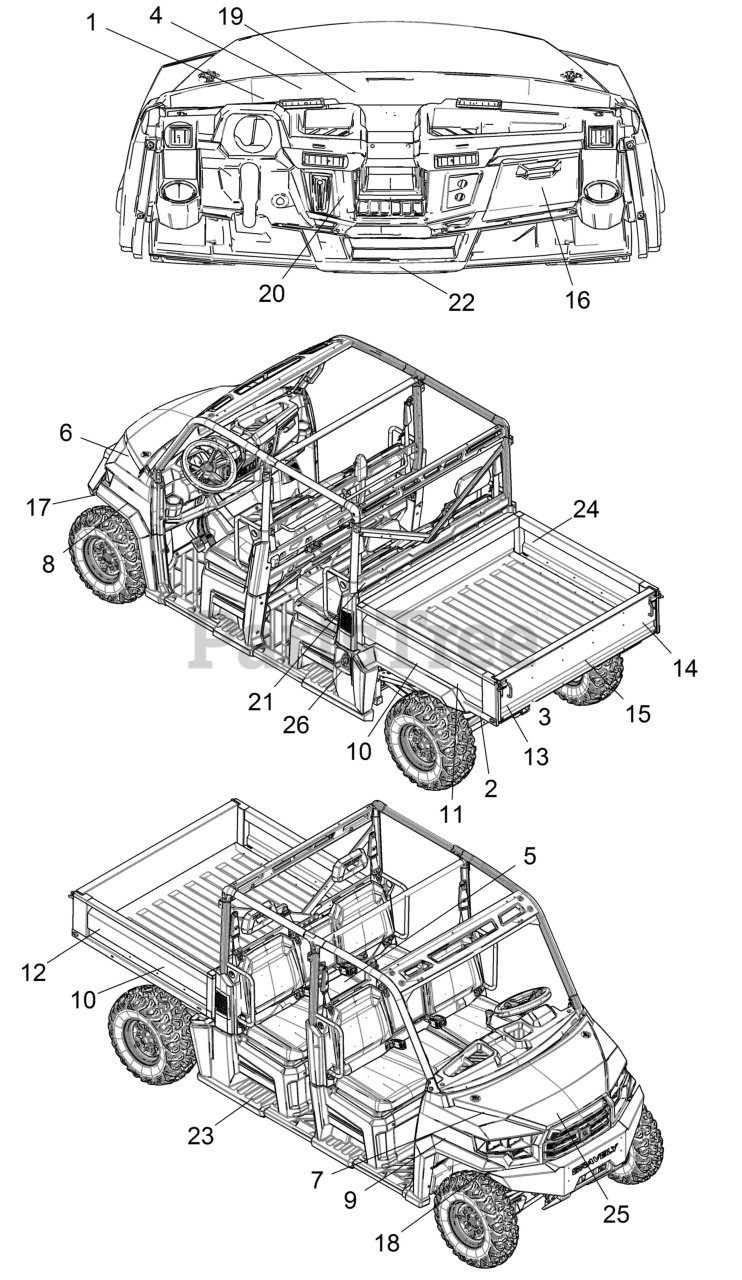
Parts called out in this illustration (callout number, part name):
1	DECAL, AGE WARNING 16
2	DECAL, REFLECTOR RED
3	DECAL-WARNING,TRAILER LOAD
4	LABEL, OPEI COMPLIANCE
5	DECAL, WARNING, PULLEY
6	DECAL, HOOD TOP DIESEL LH
7	DECAL, HOOD TOP DIESEL RH
8	DECAL, HOOD SIDE ATLSJSV, LH
9	DECAL, HOOD SIDE ATLSJSV, RH
10	DECAL, BOX SIDE GRAVELY
11	DECAL, BOX,SIDE, 6000, LH
12	DECAL, BOX,SIDE, 6000, RH
13	DECAL, TAILGATE ATLSJSV, LH
14	DECAL, TAILGATE AWD RH
15	DECAL, TAILGATE GRAVELY CENTER
16	DECAL, GLOVEBOX COVER
17	DECAL, REFLECTOR AMBER LH
18	DECAL, REFLECTOR AMBER RH
19	DECAL, WARNING DISC GRAVELY
20	DECAL, CAUTION SHIFT/BRAKE
21	DECAL, ROPS, 6000
22	DECAL,WARNING PASS/TIRE PRESS
23	DECAL NOT A STEP
24	DECAL, WARN, NEVER CARRY FUEL
25	DECAL-COOLANT
26	DECAL, WARN FUEL TRANSPORT
